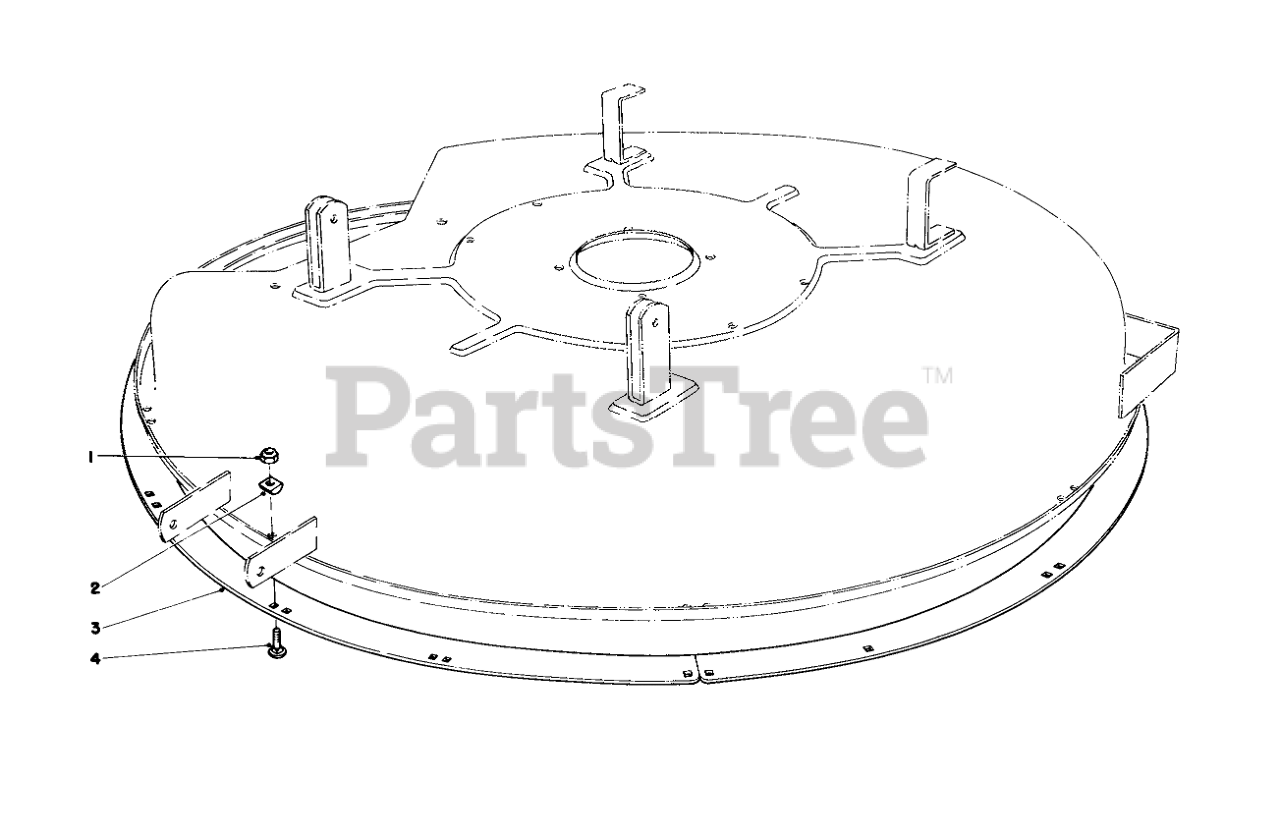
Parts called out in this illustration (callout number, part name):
1	NUT-LOCK, NI
2	Spacer-Deck Ring
3	DECK RING B
4	BOLT-CARR
